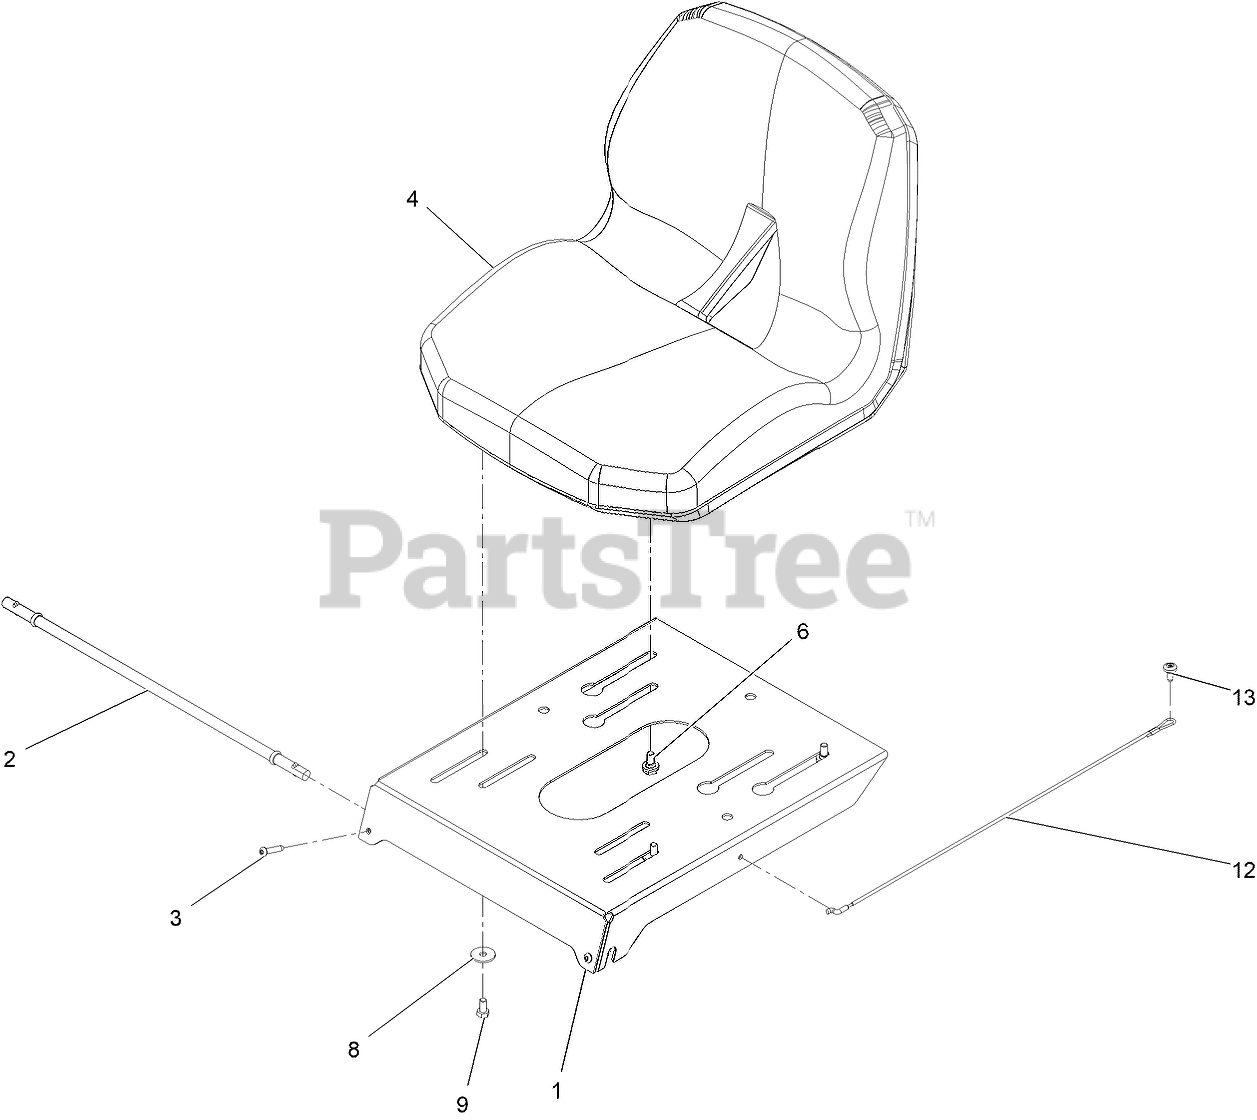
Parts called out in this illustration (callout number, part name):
2	ROD-PIVOT
3	SCREW-TTH, THREAD ROLLING
4	SEAT-16 IN
6	BOLT-SHOULDER,HFH
8	WASHER-PIVOT
9	SCREW-HH
12	CABLE-LANYARD
13	SCREW-SHOULDER
